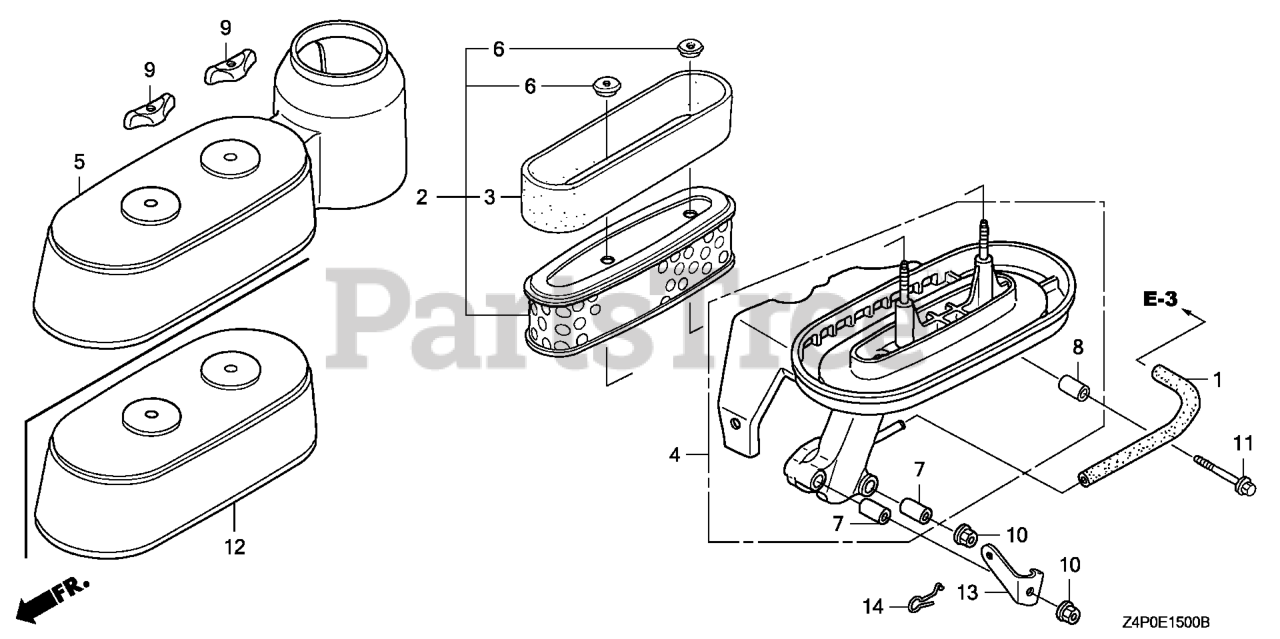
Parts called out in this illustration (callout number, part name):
1	TUBE, BREATHER
2	ELEMENT, AIR CLEANER
3	FILTER (OUTER)
4	HOUSING, AIR CLEANER
6	GROMMET, AIR CLEANER
7	COLLAR, AIR CLEANER
8	COLLAR B, AIR CLEANER
9	NUT, AIR CLEANER
10	NUT, FLANGE (6MM)
11	BOLT, FLANGE (6X35)
12	COVER, AIR CLEANER
